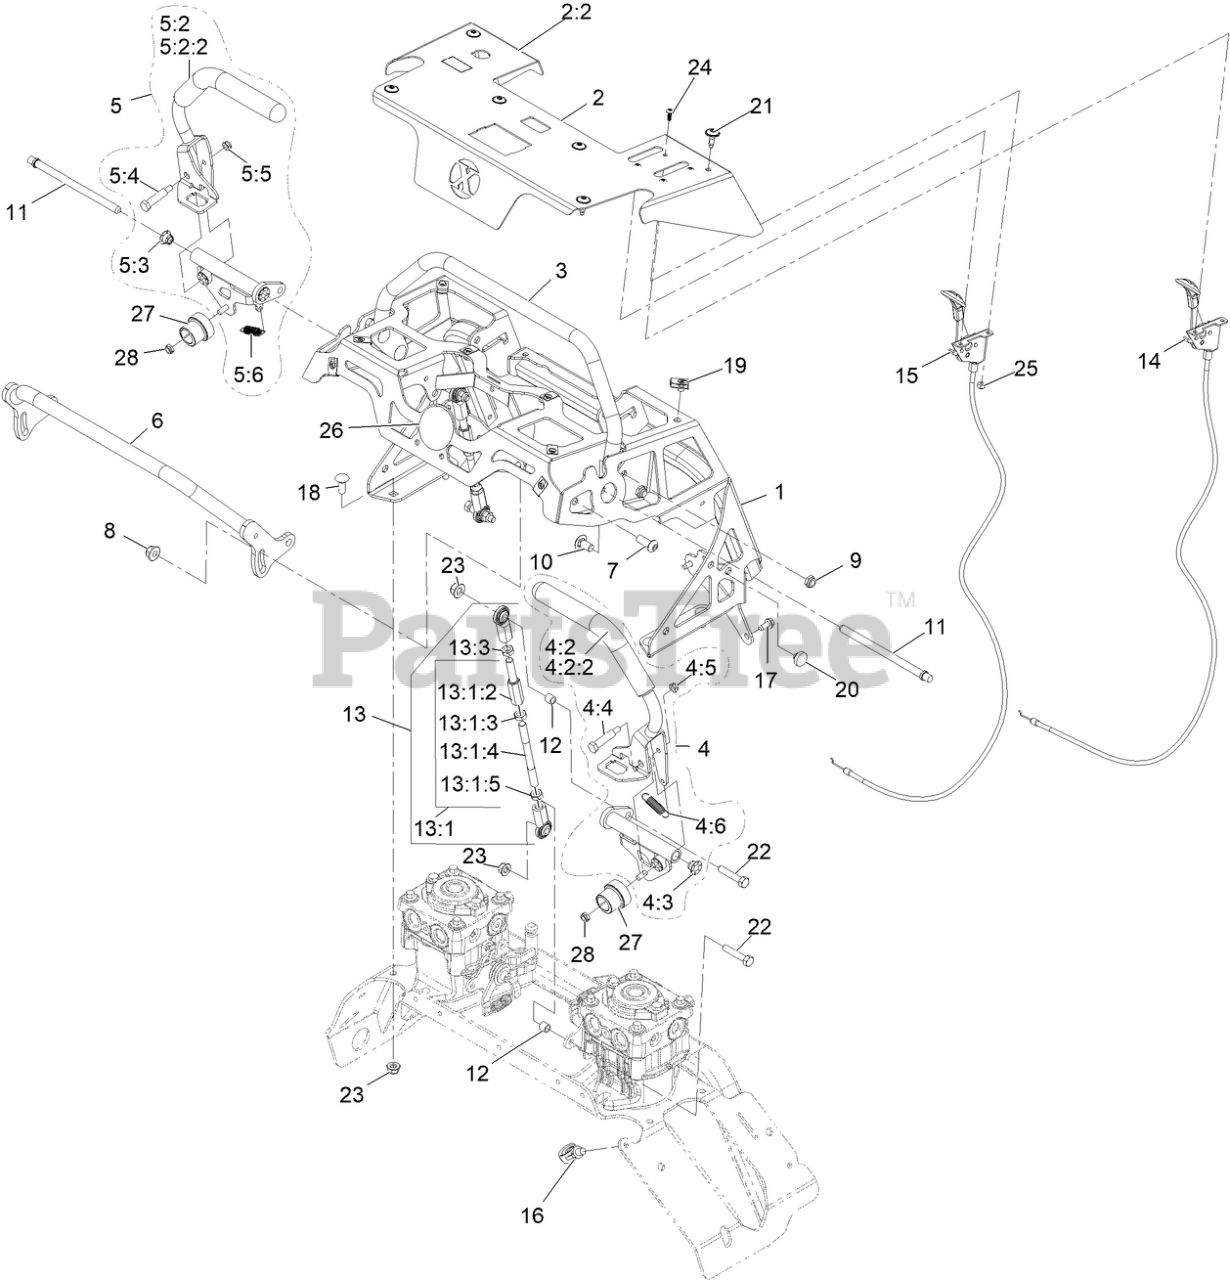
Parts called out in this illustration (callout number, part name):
1	ASM, CONTROL TOWER W/ DECAL
2	ASM, CONTROL PANEL W/ DECALS
2:2	DECAL-CONTROL PANEL NON-EFI
3	WELD, REAR REF BAR
4	ASM, MOTION CONTROL, LT
4:2	ASM, LT CONTROL LEVER W/ GRIP
4:2:2	GRIP, DRIVE LEVER
4:3	BEARING, IGUS
4:4	BOLT-SHOULDER
4:5	NUT-LOCK, NI
4:6	SPRING-EXTENSION
5	ASM, MOTION CONTROL, RT
5:2	ASM, RT CONTROL LEVER W/ GRIP
5:2:2	GRIP, DRIVE LEVER
5:3	BEARING, IGUS
5:4	BOLT-SHOULDER
5:5	NUT-LOCK, NI
5:6	SPRING-EXTENSION
6	WELD, FRONT REF BAR
7	SCREW-HSBH
8	NUT-HF, NI
10	SCREW-CARR
11	PIN, PIVOT
13	ASM, LINKAGE
13:1	ASM, Motion Control Link
13:1:2	ROD-ADJUSTMENT
13:1:3	NUT-HEX JAM, LH
13:1:5	NUT-HJ
13:3	NUT-HJ
14	CONTROL, CHOKE
15	CONTROL, THROTTLE
16	CLIP-TIE
17	SCREW-HWH
18	SCREW-CARR
21	SCREW, TORX
22	SCREW-HH
23	NUT-HF, NI
24	SCREW, BHCS
25	NUT-LOCK, NI
26	DECAL-COVER
28	NUT-LOCK, NI
